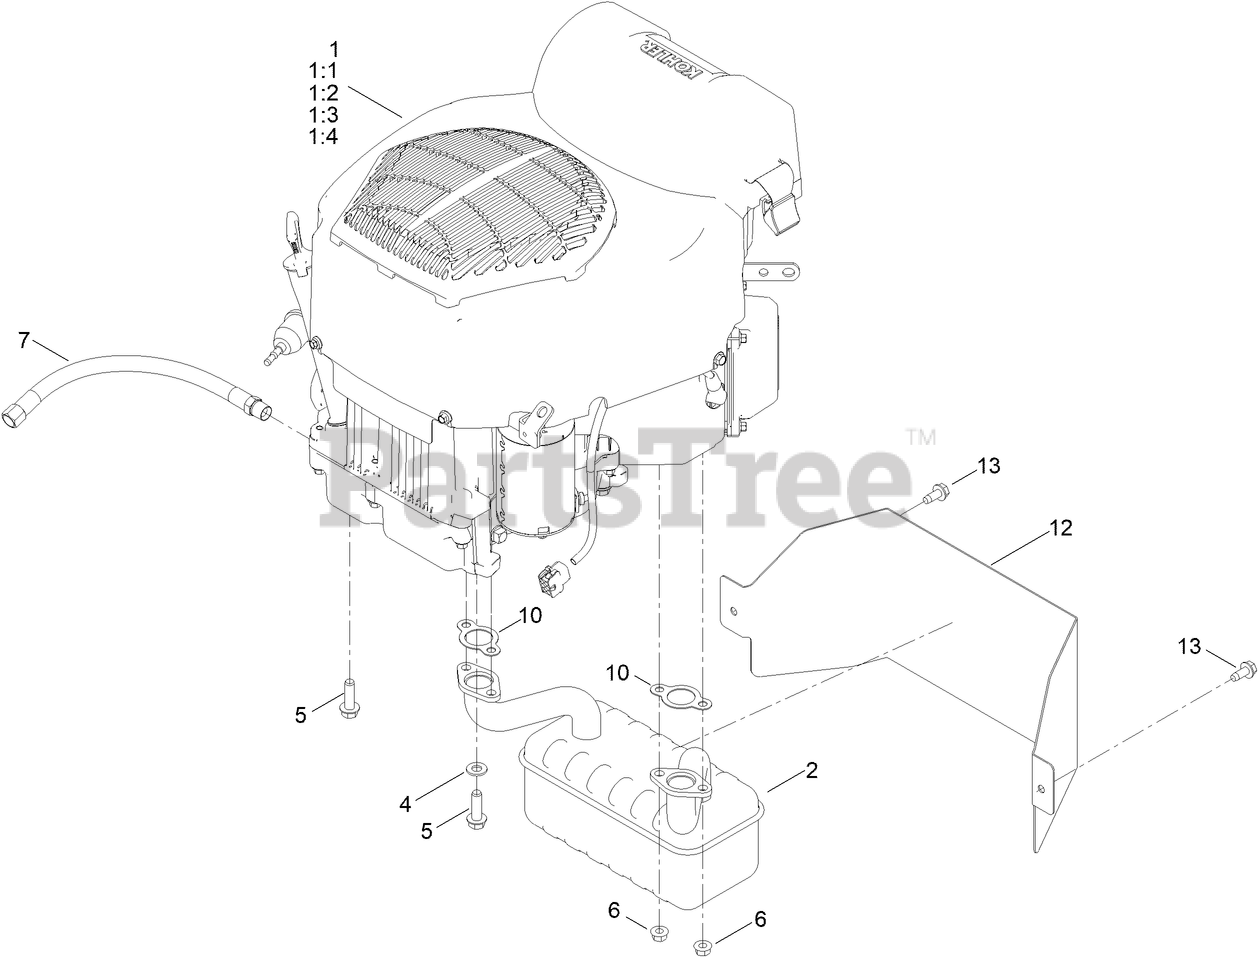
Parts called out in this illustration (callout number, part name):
1:1	FILTER-OIL
1:2	Filter-Fuel
1:3	PLUG-SPARK
1:4	FILTER-AIR, PAPER
2	MUFFLER
4	WASHER-FLAT
5	BOLT-HH
7	TUBE-DRAIN, OIL
10	GASKET-EXHAUST
12	HEAT SHIELD - MUFFLER
13	SCREW-HWHTF
